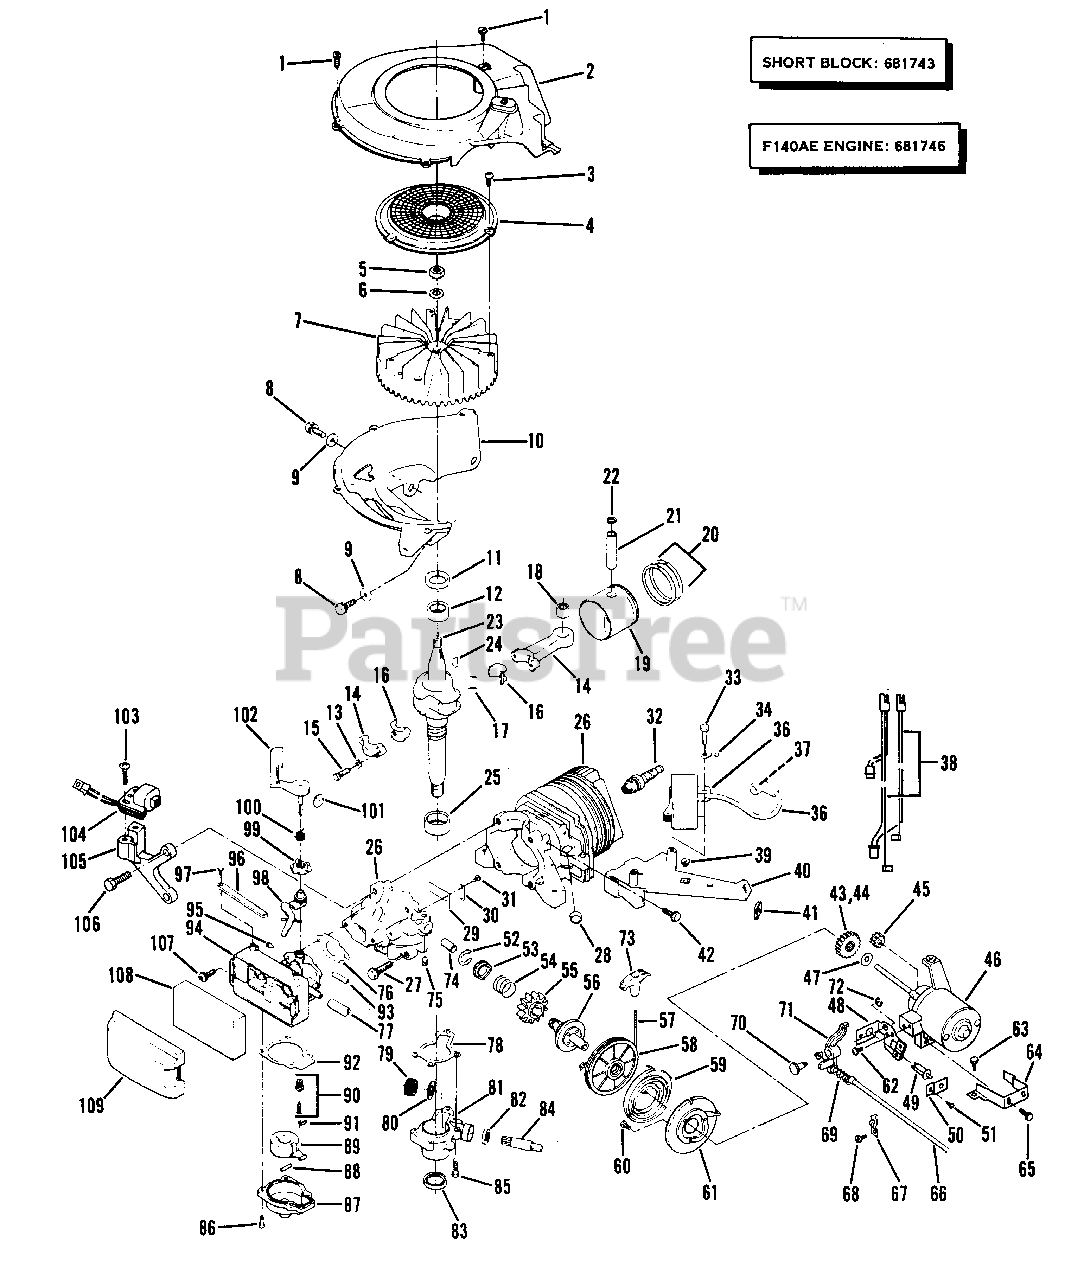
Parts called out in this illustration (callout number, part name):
1	Screw
2	Air Baffle & Eyelet Assembly
3	Screw-Flywheel Screen
4	Screen-Flywheel
5	Nut-Flywheel
6	Lockwasher
7	Flywheel Assembly
8	Screw
9	Washer
10	Base-Shroud
11	Oil Seal-Upper
12	Bearing-Upper
13	Lockplate
14	Connecting Rod Assembly
15	Screw
16	Liner-Split
17	Needle Bearing Set
18	Bearing Assembly
19	Piston & Ring Set
20	Ring Set
21	Wrist Pin
22	Retaining Ring
23	Crankshaft
24	Key-Flywheel
25	Bearing-Lower
26	Cylinder & Crankcase Cover Assembly
27	Screw-Cover to Crankcase
28	Plug
29	Reed
30	Plate-Reed Hold Down
31	Screw-Reed to Crankcase Cover
32	Spark Plug
33	Screw-C.D. Mounting
34	Terminal-Ignition
35	C.D. Ignition Module & Lead Assembly
36	High Tension Lead
37	Spring Terminal
38	Wire Harness & Terminal Assembly-Battery
39	Grommet-C.D. Bracket
40	Bracket-C.D. Mounting
41	Clip-"U"
42	Screw
43	Gear & Clutch Assembly
44	Gear-Driven
45	Pinion-Motor Shaft
46	Motor & Gear Housing Assembly
47	Thrust Washer
48	Bracket
49	Switch Assembly
50	Plate-Switch Retaining
51	Screw
52	Ring-Retaining
53	Stopwasher
54	Spring-Pinion Return
55	Pinion
56	Clutch Assembly
57	Rope-Starter
58	Pulley & Clutch Assembly
59	Spring-Rewind
60	Screw-Cover to Housing
61	Gear Cover Assembly
62	Screw
63	Screw
64	Bracket-Starter Mounting
65	Screw-Bracket to Motor
66	Cable-Interlock
67	Clip
68	Screw-Clip-Cable
69	Spring
70	Pin-Interlock
71	Lever-Interlock
72	Retaining Ring
73	Handle-Starter-Manual
74	Sleeve-Starter Pin
75	Set Screw-Starter Assembly
76	Gasket-Carburetor to Crankcase Cover
77	Fuel Line
78	Gasket-Gear Box
79	Gear
80	Washer-Thrust
81	Gear Box Assembly
82	Seal
83	Oil Seal-Lower
84	Driveshaft
85	Screw-Gear Box
86	Screw-Float Chamber
87	Float Chamber
88	Pin-Float
89	Float
90	Float Valve & Seat
91	Clip
92	Gasket
93	Tube-Primer
94	Carburetor Body
95	Screw-Altitude Adjustment
96	Retainer-Speed Control Lever
97	Screw
98	Speed Control Lever
99	Collar
100	Spring
101	Disk-Throttle
102	Air Vane & Shaft
103	Screw-Alternator Mounting
104	Alternator Assembly
105	Bracket-Alternator
106	Screw-Alternator Bracket Mounting
107	Screw-Carburetor Mounting
108	Element-Air Filter
109	Cover-Air Filter
